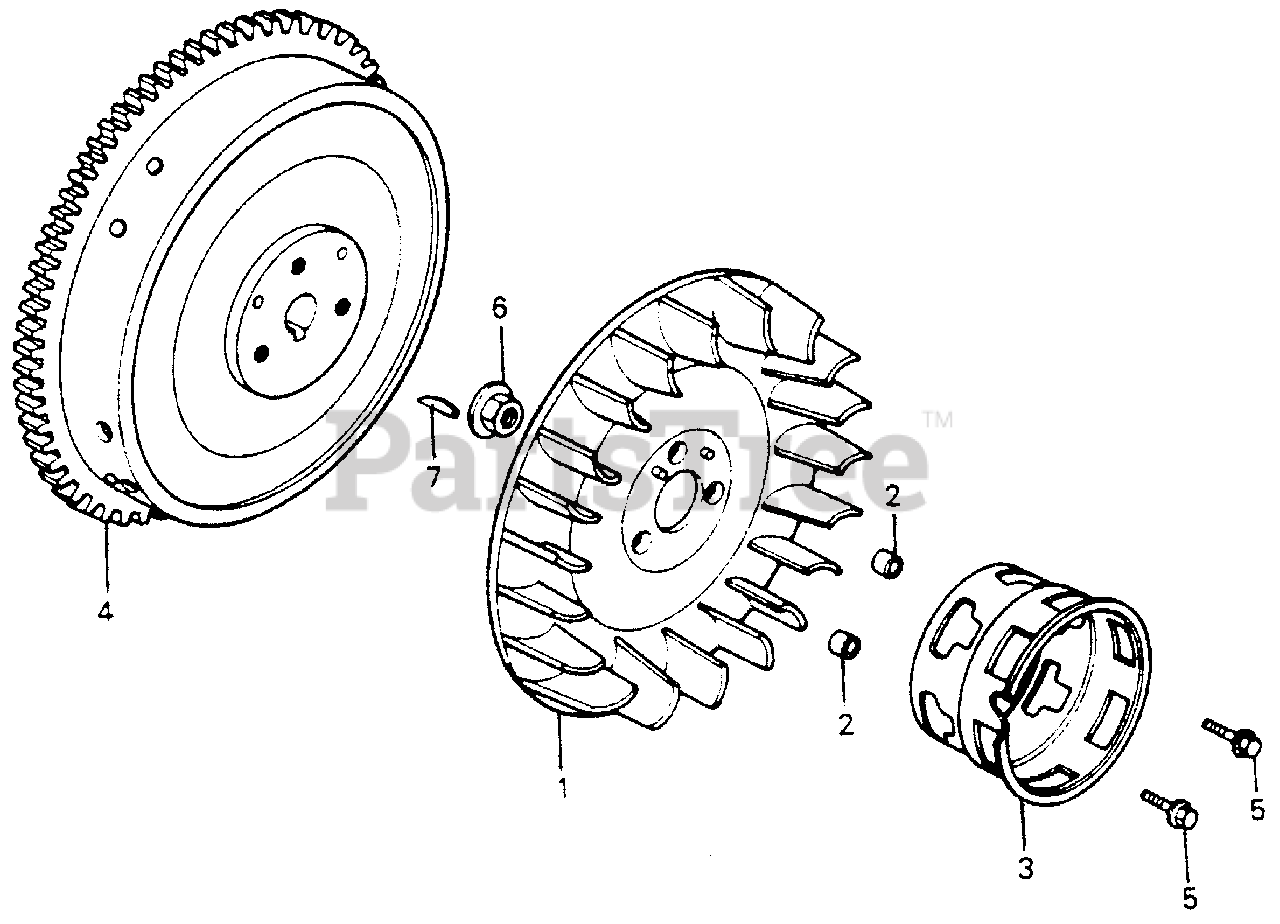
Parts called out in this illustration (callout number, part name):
1	FAN, COOLING
2	COLLAR, FAN
3	PULLEY, STARTER
4	FLYWHEEL (BREAKER)
5	BOLT, FLANGE (6X16)
6	NUT, SPECIAL (16MM)
7	KEY, SPECIAL WOODRUFF (25X18)
